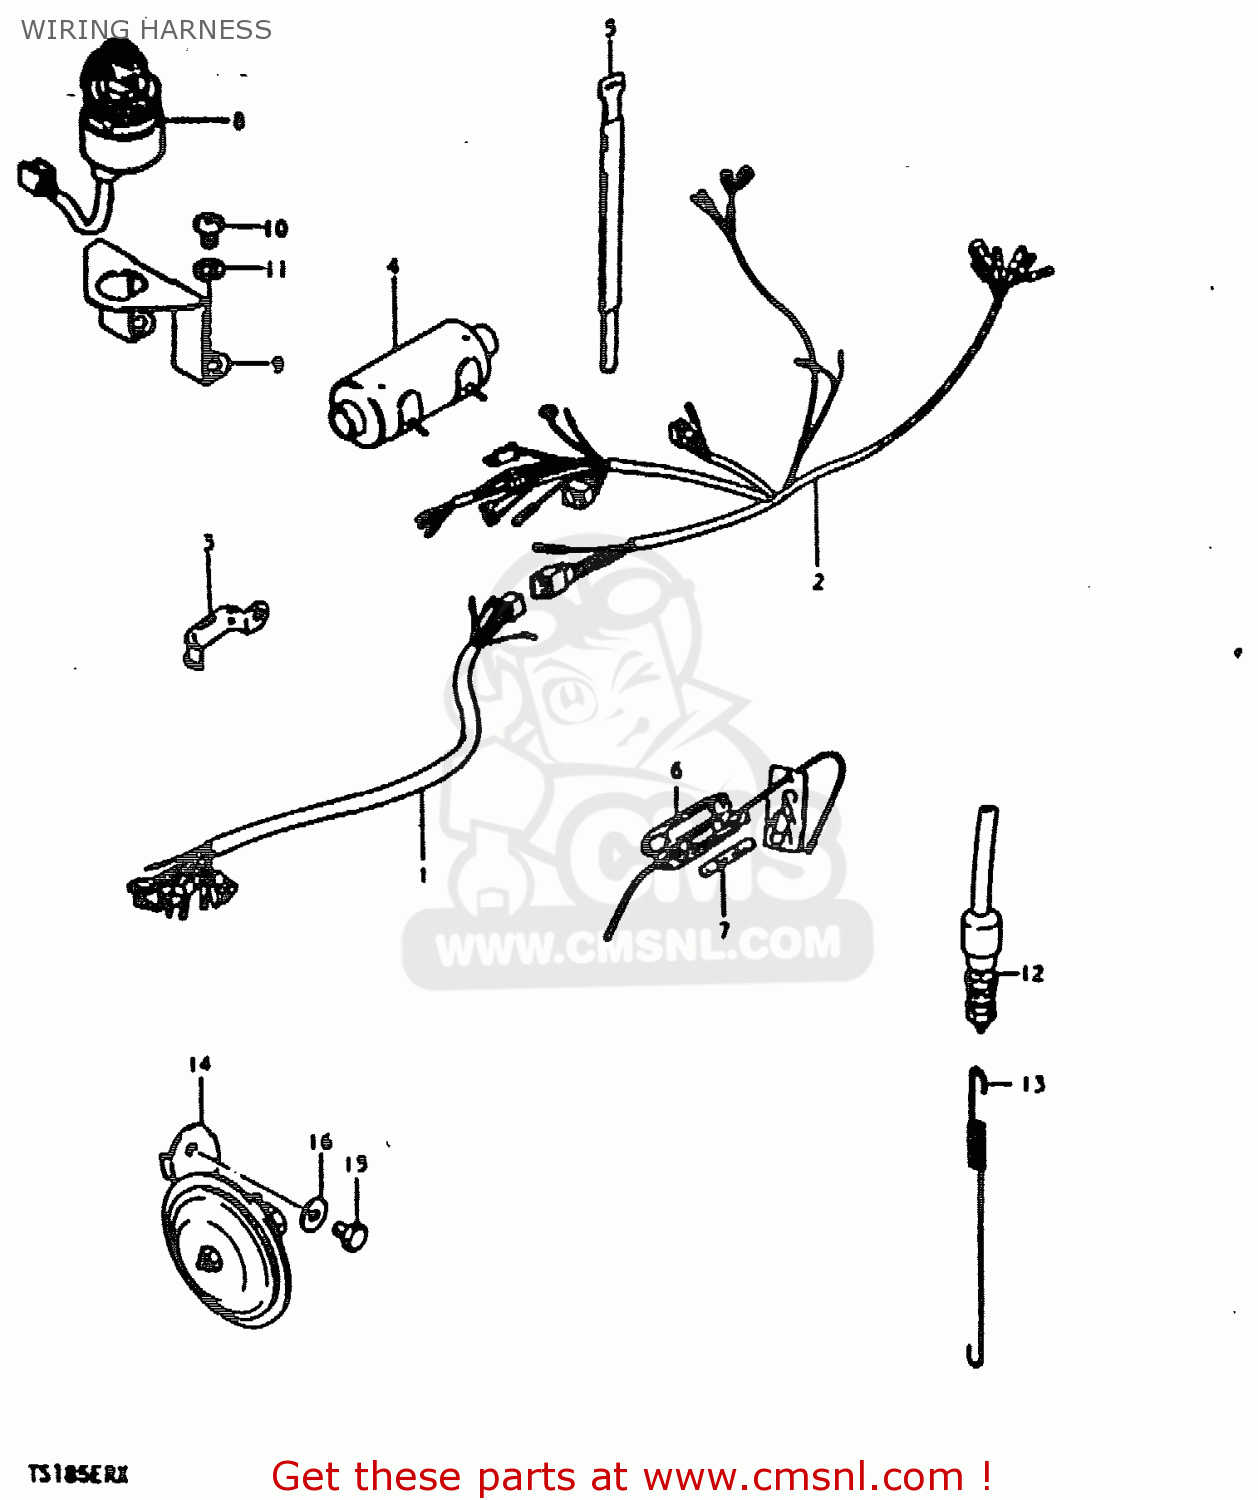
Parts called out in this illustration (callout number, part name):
1	HARNESS,WIRING NO.1
2	WIRING HARNESS NO.2
3	CLAMP
4	BOOT,WIRING HARNESS
5	CLAMP
6	BOX ASSEMBLY,FUSE
7	FUSE(15A)
8	SWITCH ASSY, IGNITION
9	BRACKET,IGNITION SWITCH
10	SCREW
11	LOCK WASHER
12	SWITCH ASSEMBLY,STOP LAMP
13	SPRING
14	HORN ASSEMBLY
15	BOLT
16	WASHER
